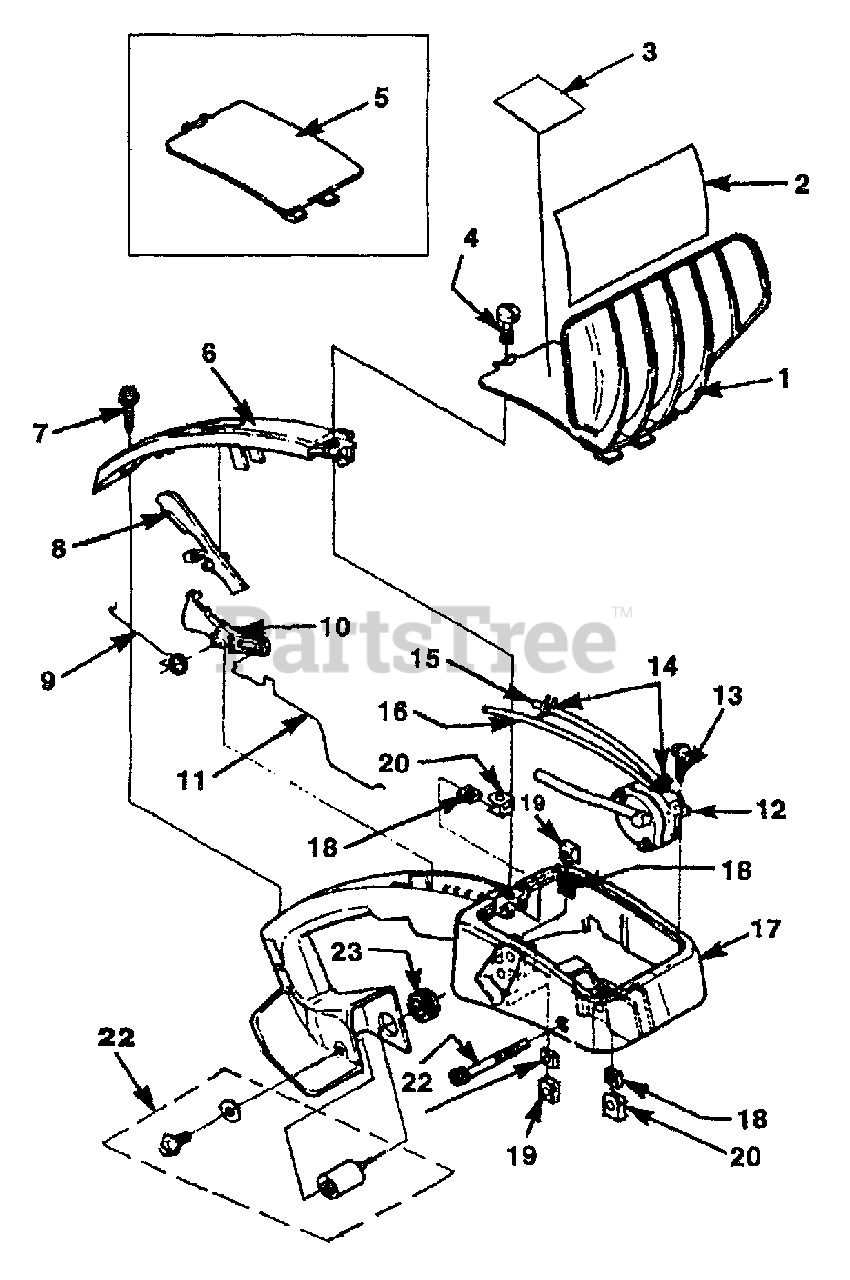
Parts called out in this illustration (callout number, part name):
1	HANDGUARD w/Cover
2	SCREW-Retaining
3	DECAL-Warning
4	DECAL-Warning
5	AIR FILTER COVER
6	COVER-Handle
7	SCREW-Thread Form. (10-24 X 3/4")
8	INTERLOCK-Trigger
9	SPRING-Torsion
10	TRIGGER-Throttle
11	ROD-Throttle
12	OIL PUMP-Complete
13	SCREW-Plastite (10 X 5/8")
14	CLAMP (Oil Outlet Line)
15	TUBING-Rubber (4 1/2")
16	TUBING-Rubber (6 1/4")
17	CARBURETOR CHAMBER
18	NUT-Square
19	RETAINER NOT
20	RETAINER NUT
22	VIBRATION ISOLATOR KIT
23	GROMMET
